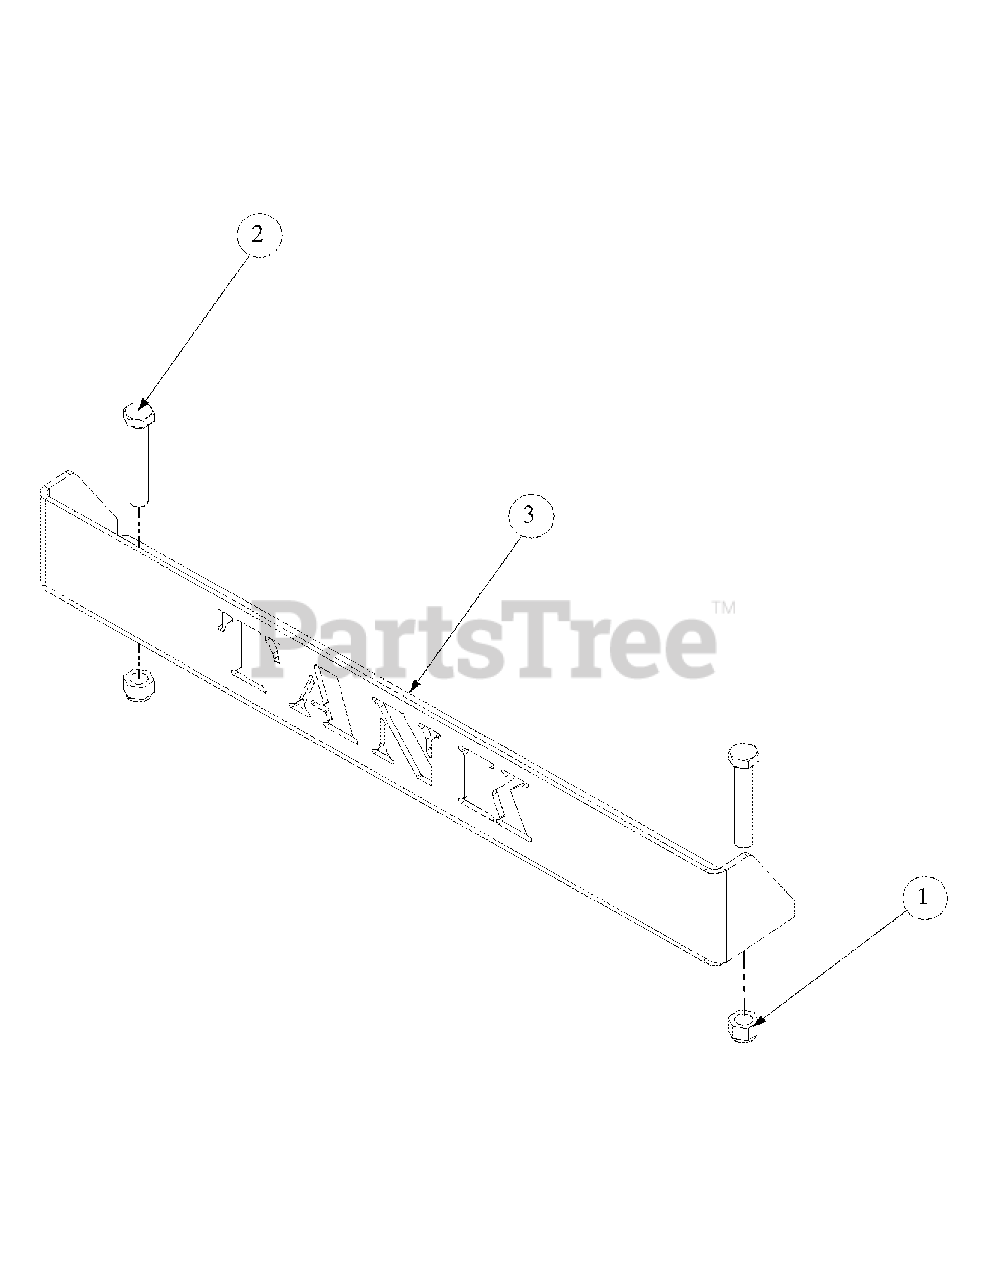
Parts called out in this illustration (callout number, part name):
1	Hex Nut, 1/2-13, Insert Lock
2	HHCS, 1/2-13, 3.00
3	Rear Bumper Plate
